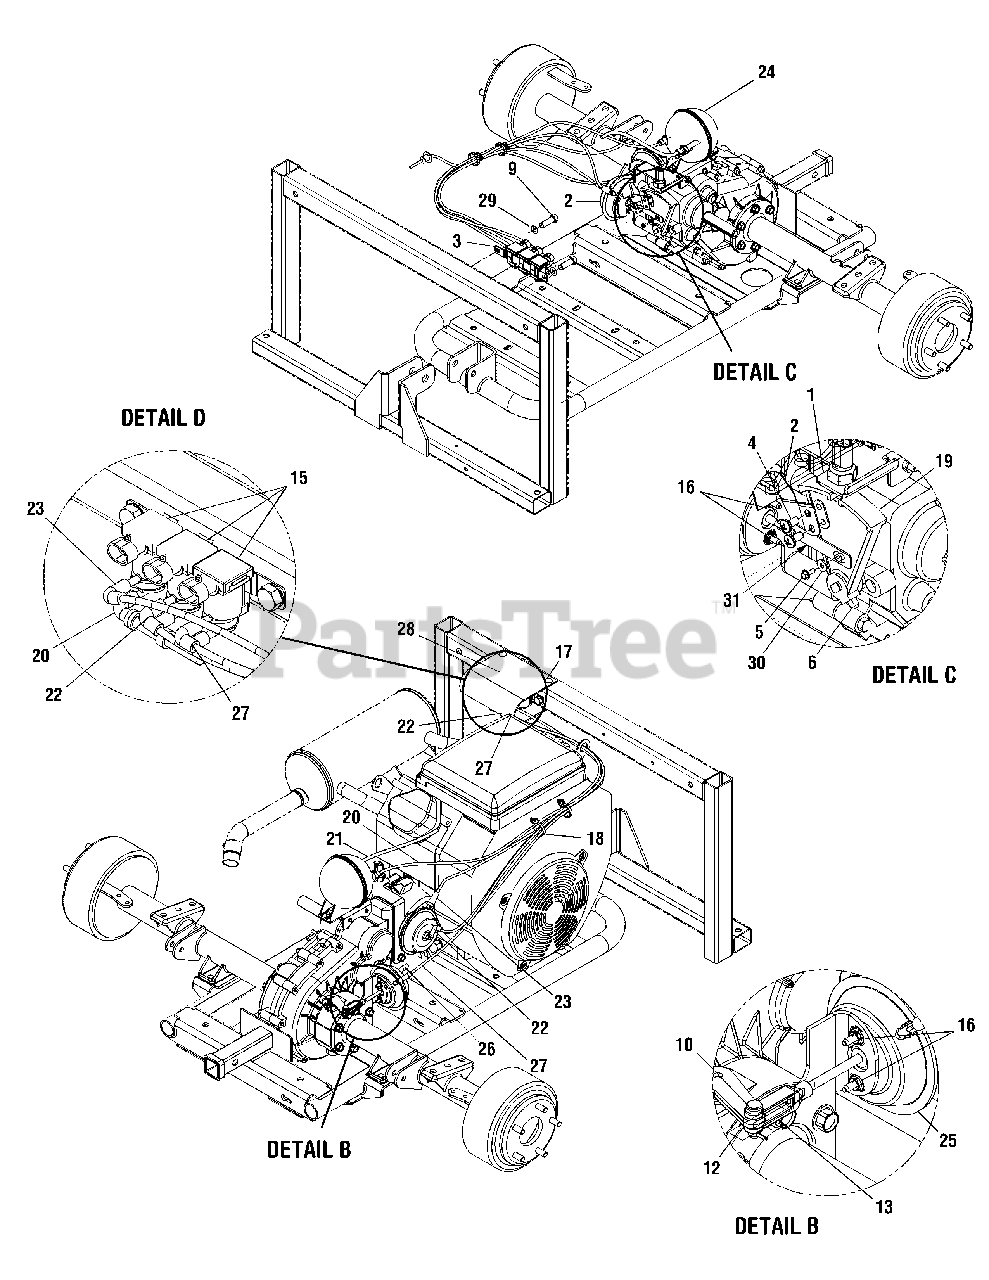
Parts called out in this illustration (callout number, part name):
1	Mounting Bracket, Vacuum Actuator
2	Bracket, Shift
3	Bracket, Vac Relay
4	Screw, 1/4-20 x.5
5	Screw, Hex. #8 - 18 .375
6	Screw, Set, 5/16-24 x .50 LG
7	Screw, 5/16-18
8	Screw, 1/4-14
9	Screw, 5/16-18 x .75 Hex
10	Pin, Yoke 1/4
11	Nut, Hex 9/16-18
12	Pin, Cotter 1/16x.750
13	Yoke, 1/4-28
14	Switch, Neutral
15	Solenoid, Kit Vacuum Actuator
16	Self Threading Nut
17	Clip, Panel Retainer
18	Cable Tie
19	Arm, Shift
21	Hose, Manifold Vacuum
22	Hose, Actuator Vacuum
23	Hose, Actuator Vacuum
24	Reservoir, Air
25	Actuator, Vac Differential Lock
26	Differential Lock, Vent
27	Hose, Vac Differential Lock Supply
28	Cover, Solenoid
29	Flat Washer, .330 x .687 x .030
30	Flat, Washer, .188 x .437 x .042
31	Actuator, Vacuum Shift
